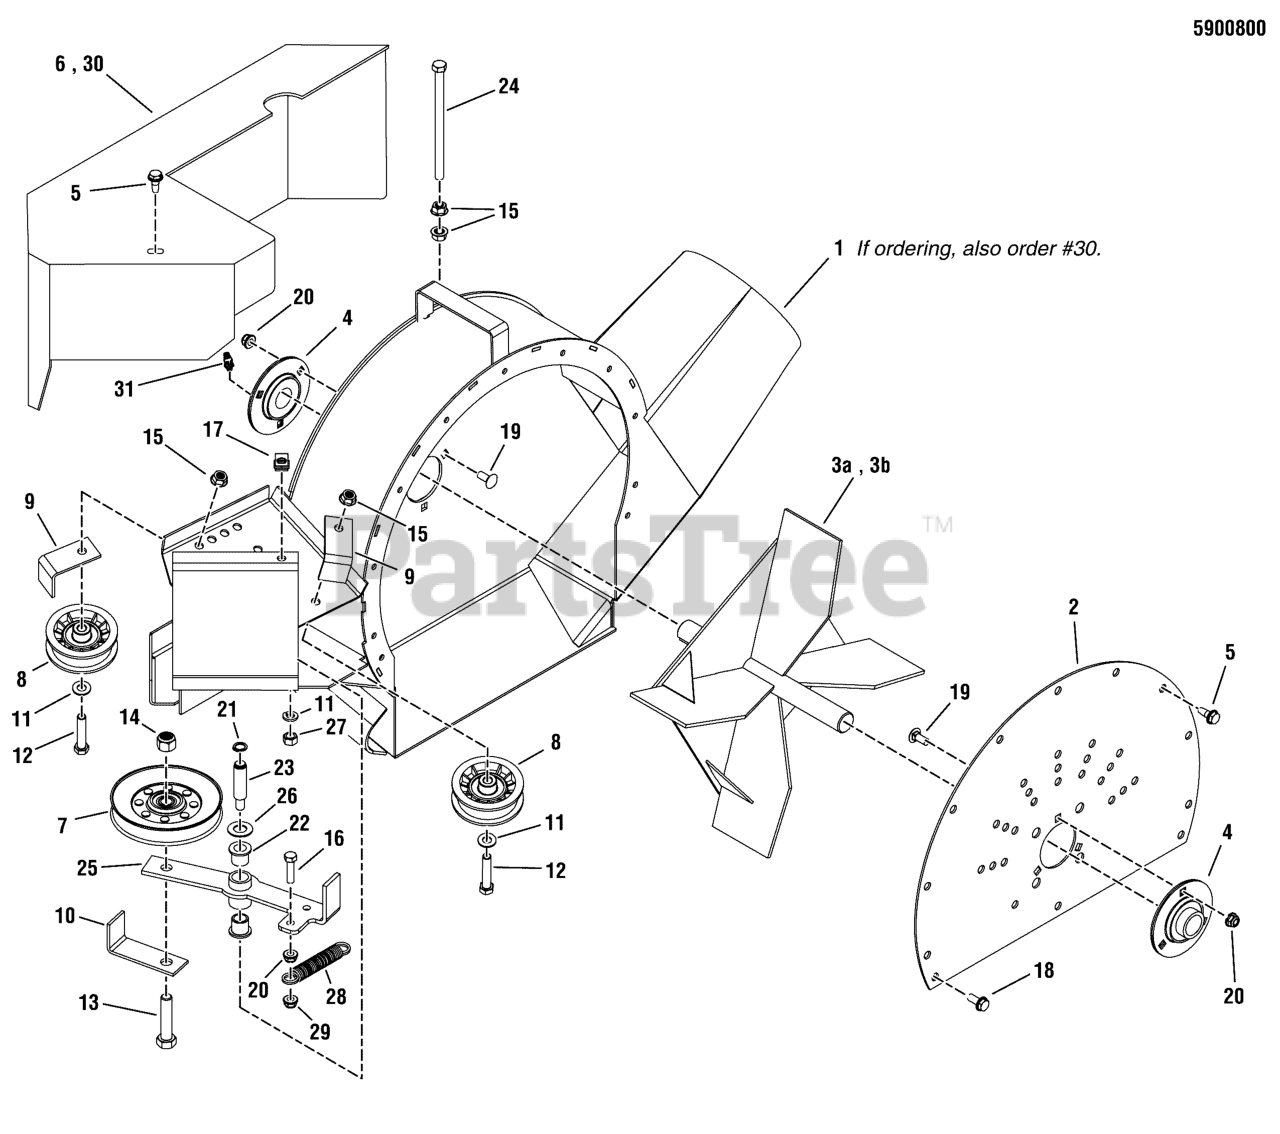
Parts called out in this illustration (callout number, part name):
1	**BLOWER HOUSING
2	BACK PLATE
4	BEARING, FLANGE, 1" Bore
5	BOLT, 5/16-18 X 3/4" Self Tap
6	BELT GUARD
7	PULLEY-IDLER-V, 4.85OB, .506 ID, ,94W, STL
8	PULLEY, IDLER, 2.75"OD X .37"ID, INSERT
9	BELT KEEPER
10	KEEPER, BELT TENSIONER
11	WASHER, 3/8 SAE
12	HHCS, 3/8-16 X 2.00, GR5, ZINC/CLEAR
13	BOLT, 1/2-13 X 2-1/4" GD5 CZ
14	NUT, Hex, Nylon Lock, 1/2-13
15	NUT, 3/8-16 Hex Large Serrated Flange
16	BOLT, 5/16-18 X 1-1/4" GD5 YZ
17	BODY CLIP, 5/16-18 7GA. MATERIAL
18	BOLT, 5/16-18 X 5/8" Self Lock
19	BOLT, 5/16-18 X 3/4, CARRIAGE, GD5, CZ
20	NUT, 5/16-18 HEX NYLOCK FLANGE NUT
21	RETAINING RING, 1/2"
22	FLANGE BEARING, 9/16"
23	IDLER STUD
24	BOLT, 3/8-16 X 6" GD5 CZ
25	ASSM, IDLER ARM, FAST-VAC - BLK (Includes bushings)
26	WASHER, FLAT, 9/16 ID, 1-1/8 OD, 98THK
27	NUT, 3/8-24 Hex Nylon Lock
28	SPRING, Extension
29	NUT, 5/16-18 Hex Center Lock
30	WELD, Fast-Vac Guard - BLK
31	GREASE FITTING, 65 DEG 1/4-28 TAPER MALE
